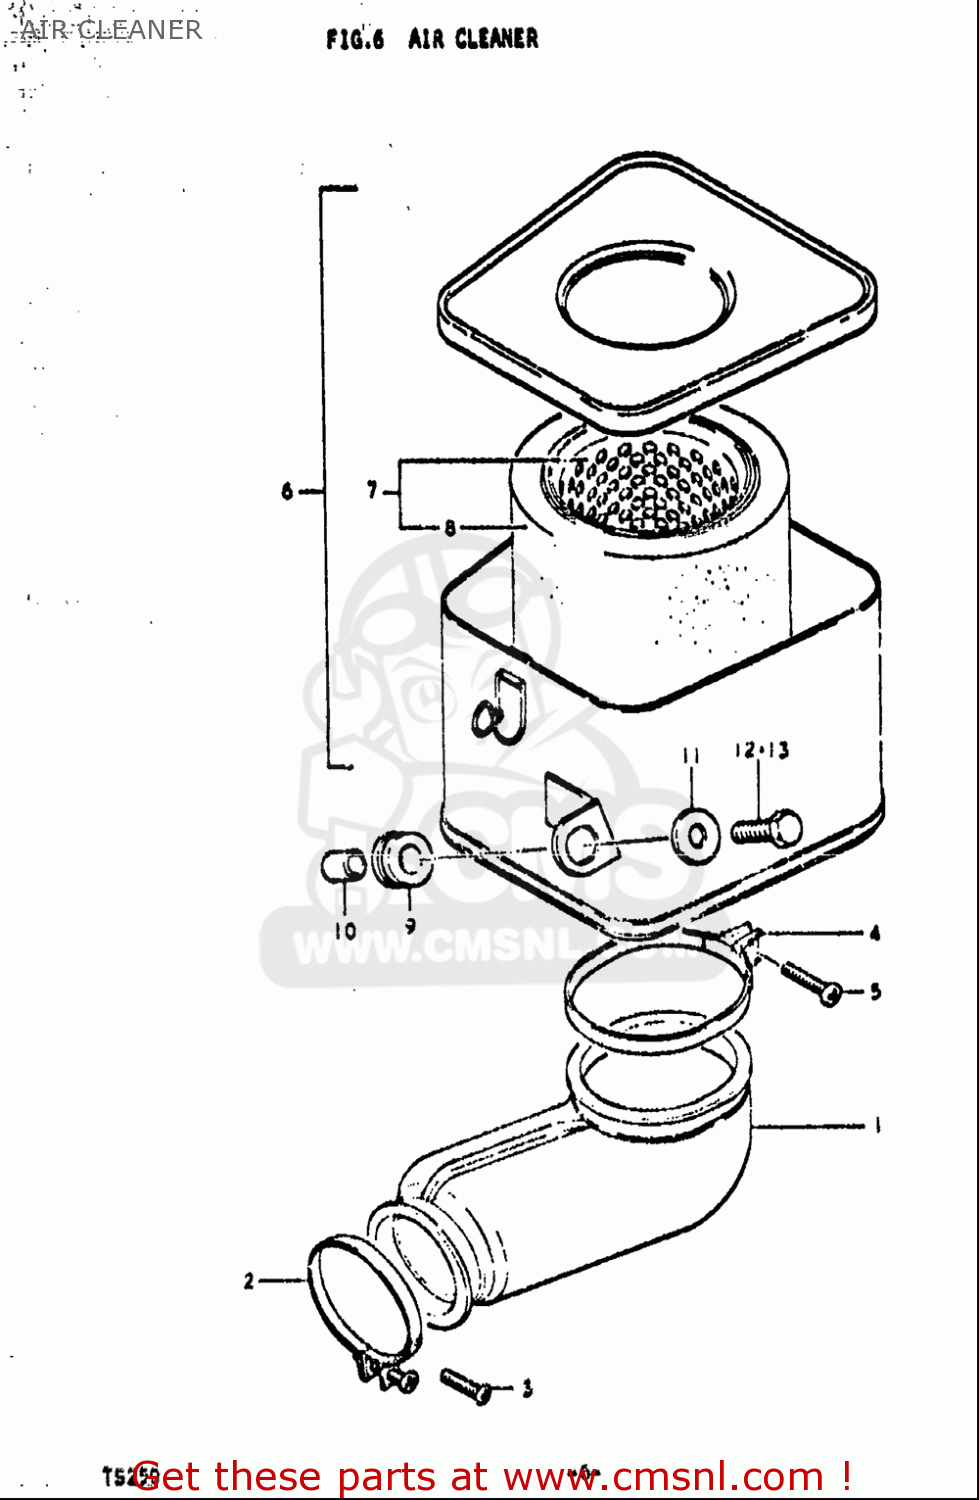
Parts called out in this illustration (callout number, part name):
1	HOSE,CARBURETOR AIR INLET
2	CLAMP
3	SCREW
5	SCREW
9	CUSHION
11	WASHER(6.5X20X1.2)
12	BOLT
